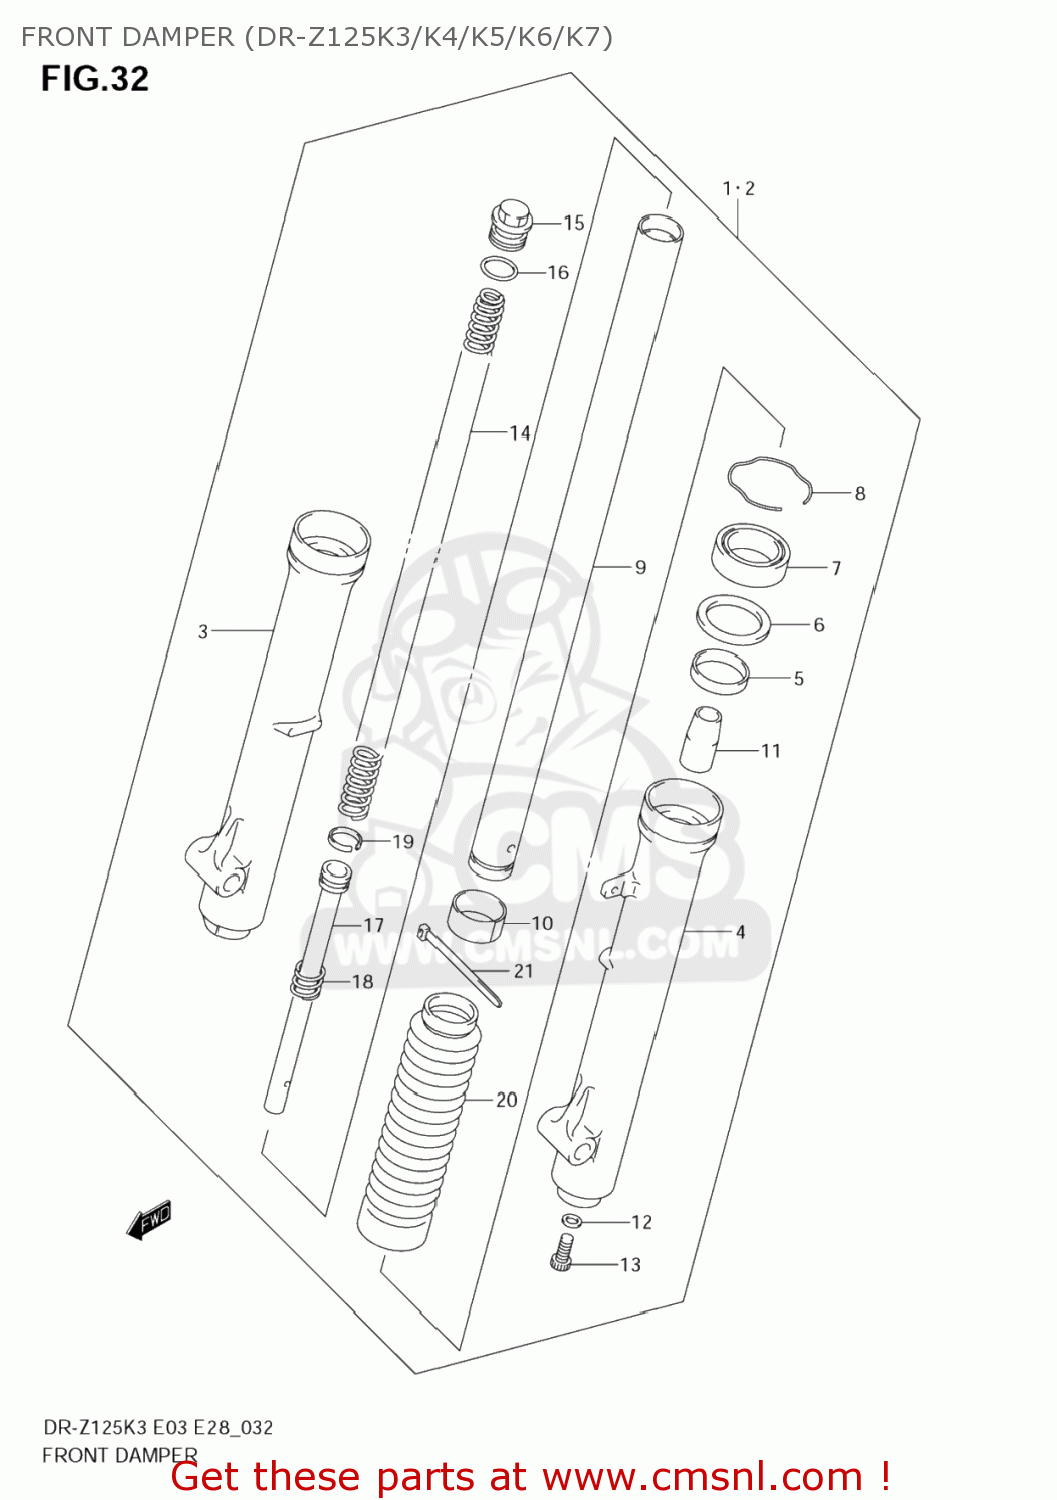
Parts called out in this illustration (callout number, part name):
1	DAMPER ASSY,FR FORK,R
2	DAMPER ASSY,FR FORK,L
3	TUBE,OUTER,R
4	TUBE,OUTER,L
5	BUSH,GUIDE
6	SPACER,SEAL
7	SEAL,OIL
8	SEAL,OIL STOPPER RING
9	TUBE,INNER
10	BUSH,SLIDE
11	PIECE,OIL LOCK
12	GASKET (NAS)
13	BOLT(8X27)
14	SPRING,FR
15	BOLT
16	O RING
17	CYLINDER
18	SPRING,REBOUND
19	RING
20	BOOT
21	BAND
